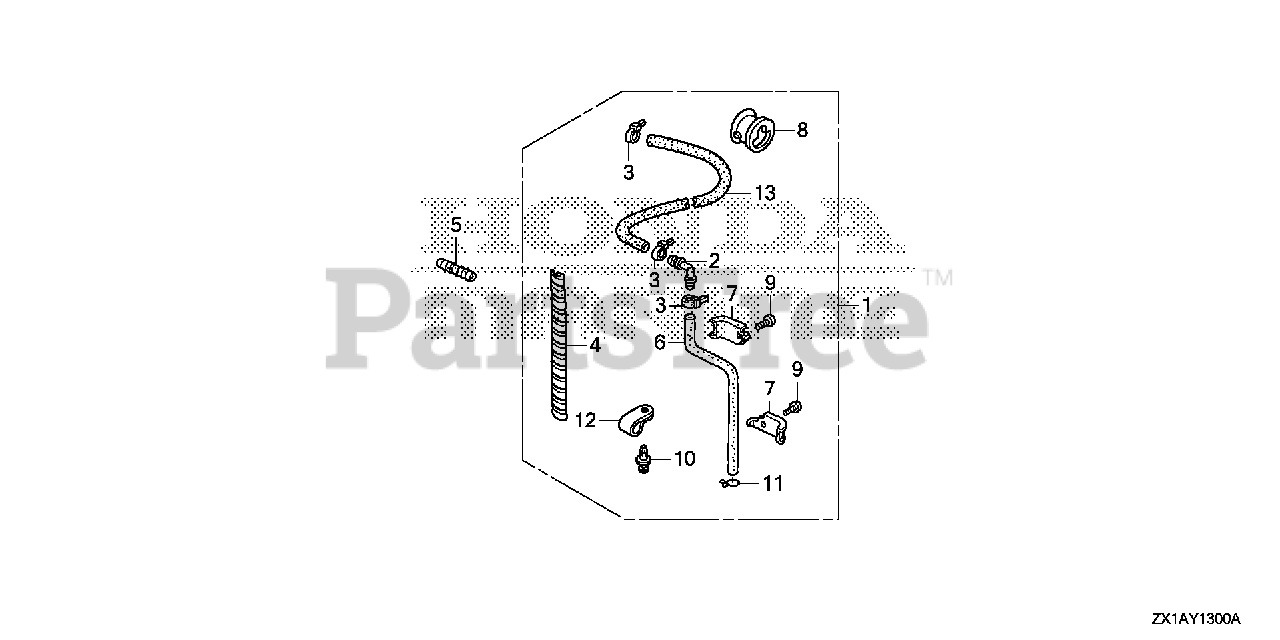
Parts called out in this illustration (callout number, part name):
1	TUBE KIT, SPEED SENSOR
2	JOINT A, BREATHER
3	BAND, WIRE
4	TUBE, SPIRAL
5	END, NIPPLE
6	TUBE, SPEED SENSOR
7	PLATE, SPEED SENSOR TUBE
8	BUSH, MOTOR CODE
9	SCREW, PAN (6X8)
10	SCREW, RIVET (5X10)
11	CLIP, TUBE (B8)
12	CLIP (14MM)
13	BULK HOSE, VACUUM (5X3000) (5X250)
